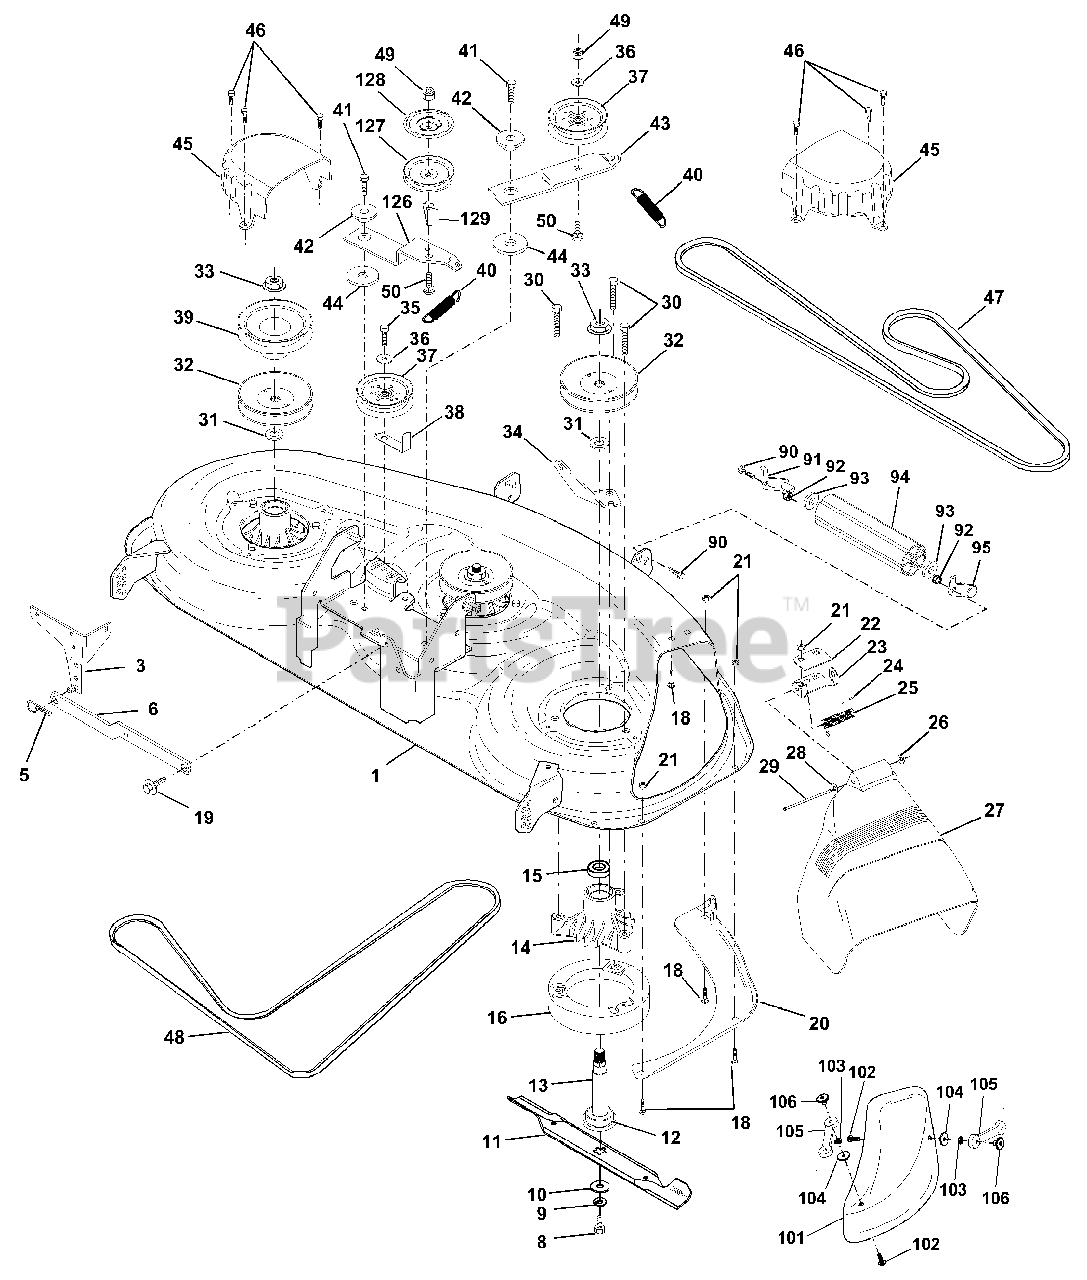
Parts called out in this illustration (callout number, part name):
1	Deck Asm., Mower 46"
3	Bracket Asm., Sway Bar
5	Retainer Spring
6	Arm, Suspension, Rear (Sway Bar)
8	Bolt, Patched 3/8-24 x 1-1/4 Gr. 8
9	Washer, Lock Hvy., Unplated 3/8
10	Washer, Hard Blade, Mower Vented
11	Blade, 46" Mower Deck
12	Bearing, Ball, Mandrel #6204
13	Shaft Asm. w/Lower Bearing
14	Housing, Mandrel
15	Bearing, Ball, Mandrel
16	Stripper, Mower Round
18	Bolt, Carriage 5/16-18 x 5/8
19	Bolt, Hex Head, Shoulder 5/16-18
20	Baffle, Vortex Mower 46"
21	Nut, Crownlock 5/16-18 UNC
22	Stiffener, Bracket
23	Bracket, Deflector
24	Cap, Sleeve
25	Spring, Torsion, Deflector
27	Shield, Deflector Mower
28	Washer 11/32 x 5/8 x 16 Ga.
29	Rod, Hinge
30	Screw, Hex Head, Thdroll
31	Washer, Spacer Mower Vented
32	Pulley, Mandrel
33	Nut, Flg. Top Lock Cntr. 9/16
34	Anchor, Spring Deck 46"
35	Screw, Thdroll 3/8-16 x 1-3/4 Tytt
36	Washer 13/32 x 13/16 x 16 Ga.
37	Pulley, Idler, Flat
38	Keeper, Belt, Idler
39	Pulley, Idler, Driven
40	Spring, Secondary 44/46/50 Vent
41	Screw, Thdroll 3/8-16 x 1-1/4 Tytt
42	Spacer, Retainer
43	Arm, Idler Secondary
44	Washer, Hardened
45	Cover, Mandrel Deck
46	Screw, Thdroll. 1/4-20 x 5/8
47	V-Belt, Mower, Secondary
48	V-Belt, Mower, Primary
49	Nut, Crownlock 3/8-16 UNC
50	Bolt, Carriage 3/8-16 x 1-1/2 Gr. 5
90	Bolt, Fin, Hex 3/8-16 UNC x 1
91	Bracket, Asm Noseroller, LH
92	Nut, Lock, Hex w/Ins 3/8-16UNC
93	Washer 17/32 x 7/8 x 16 Ga.
94	Roller, Nose 38 & 42
95	Bracket, asm Noseroller RH
101	Cover, Mulching
102	Screw
103	Washer, Lock #10
105	Latch Asm. Bagger
116	Bolt, Shoulder
117	Gauge Wheel
118	Nut, Centerlock 3/8-16 UNC
119	Washer 3/8 x 7/8 x 14 Ga.
126	Arm, Idler, Primary Deck 46"
127	Pulley, Idler, V-Groove Dim. 4.25
128	Shield, Idler
129	Keeper, Belt, Idler 46"
